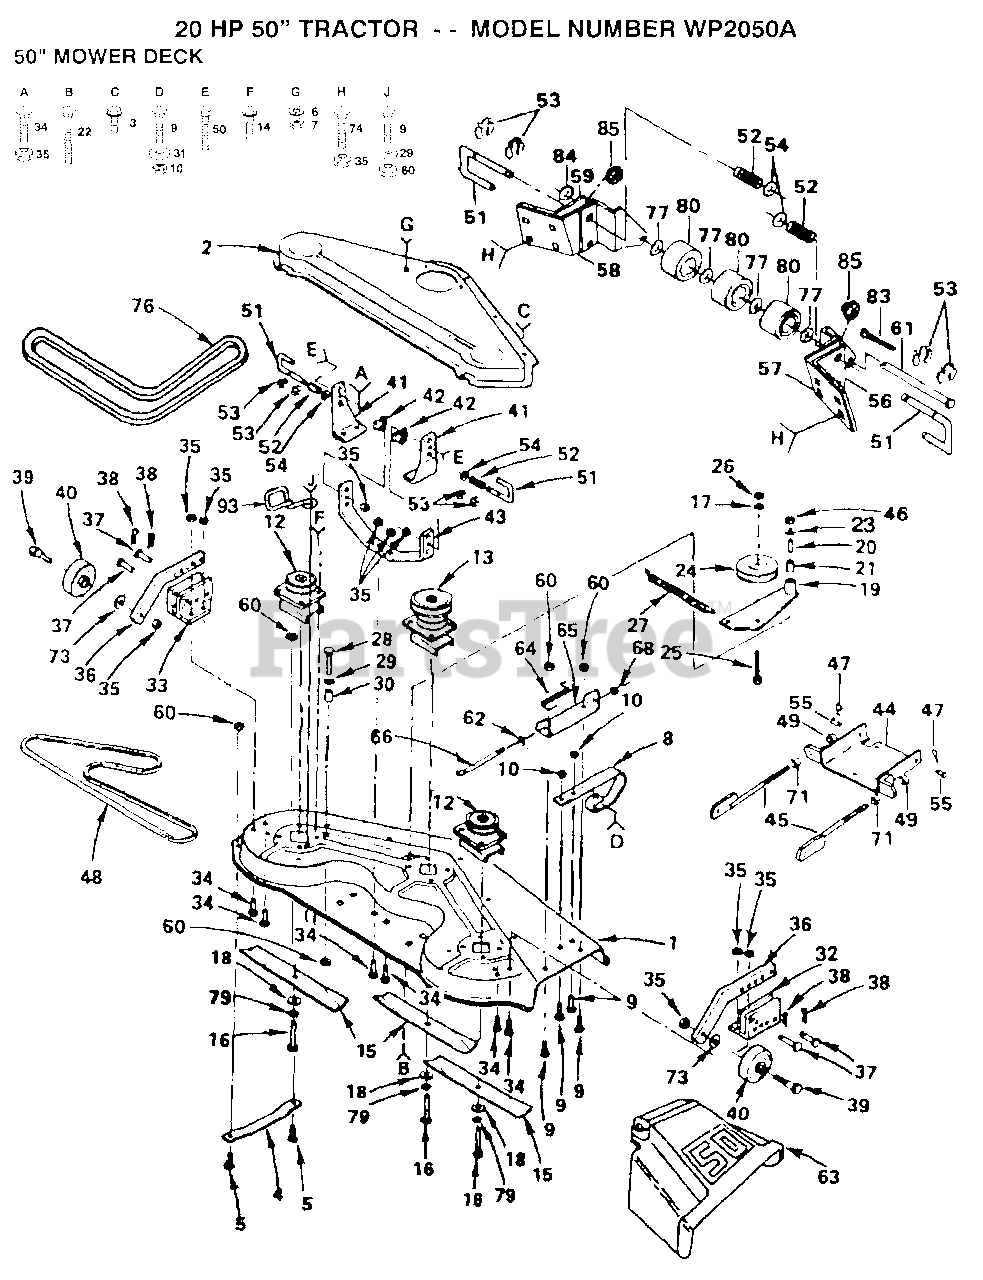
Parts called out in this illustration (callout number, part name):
2	CVR DRIVE DECK
3	SCREW LT
4	RUNNER-LH M
5	BOLT
6	LOCKWASHER
7	NUT.HEX.5/16-18
9	BOLT
13	JACKSHAFT
14	SCREW
15	"BLADE.50""STD.LIFT"
16	BOLT.3/8-24X1-1/2
17	LOCKWASHER
18	WASHER
19	ARM ASSY GT
22	BOLT
24	IDLER-FLAT T
26	NUT.HEX.3/8-16UNC
27	SPRING T
28	BOLT
29	WASHER M
30	SPACER SPLIT LT
31	WASHER
32	GUAGE WHL BRKT GT
33	GUAGE WHL BRKT GT
34	BOLT
36	GUAGE WHL BAR GT
39	BOLT M
40	WHEEL.GAGE.BLK.PL
41	SUSP BRKT GT
42	SPACER GT
43	SUSP BRACE GT
45	BRACKET.SUSPEN.AS
46	JAM NUT TI
47	RETAINER.SPRING
48	V-BELT M
49	NUT LTV
50	BOLT
51	RELEASE PIN GT
52	SPRING M
53	KLIP RING
55	CLEVIS PIN GT
56	BRACKET T
57	BRACKET T
58	BRACKET T
59	BRACKET T
61	PIVOT PIN T
62	WASHER
63	DEFLECTOR
66	ROD-HINGE T
68	NUT PUSH M
71	NUT
73	WASHER
74	BOLT
76	BELT-V.93.5.MWR
77	WASHER T
80	ROLLER T
83	COTTER PIN
85	SPACER T
93	BELT RETIANER
